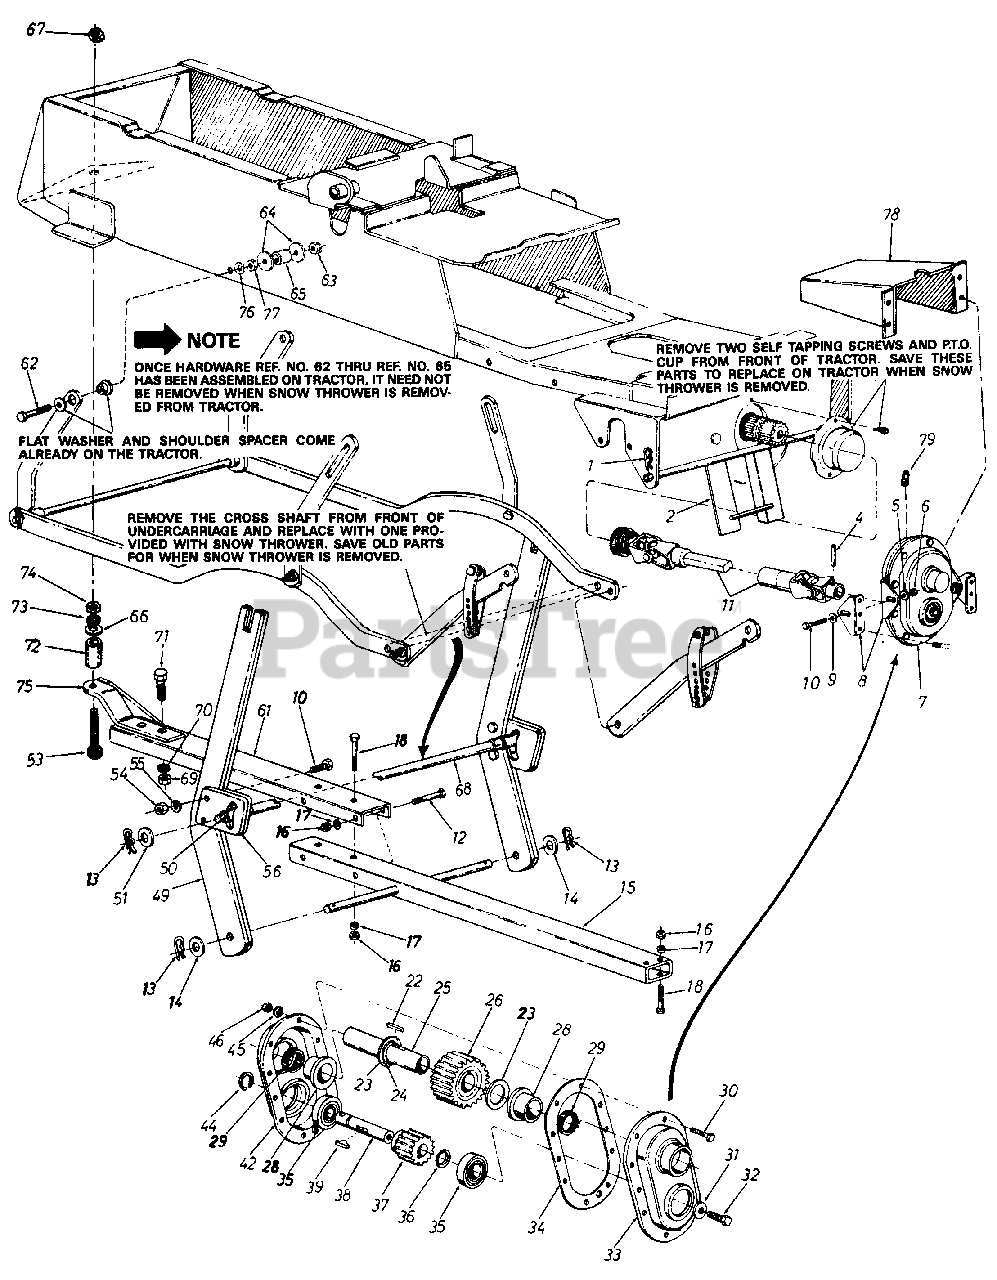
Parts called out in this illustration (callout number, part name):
1	Intern. Cotter Pin 3/4" Dia.
2	Guide Bracket Ass'y.
4	Roll Pin Spirol 5/16" Dia. x 2.5" Lg.
5	Belleville Wash. .341" I.D. x .88" O.D.
6	Hex Nut 5/16-18 Thd.*
7	Gear Box Ass'y. Comp.
8	Gear Box Support Brkt.
9	Belleville Wash. .341" I.D. x .88" O.D.
10	Hex Bolt 5/16-18 x 1.25" Lg. (Grade 5)
11	Universal Drive Shaft Ass'y.
12	Hex Bolt 3/8-24 x 4.50" Lg.*
13	Hair Pin Cotter
14	Fl.-Wash. .75" I.D. x 1.5" O.D.
15	Lift Shaft Ass'y.
16	Hex Ins. Jam L.-Nut 3/8-24 Thd.
17	L.-Wash. 3/8" I.D.*
18	Hex Bolt 3/8-24 x 2.75" Lg.
22	Hi-Pro Key 1/4" x 7/8" Dia.
23	Fl.-Wash. 1.31" I.D. x 2.00" O.D. x .060
24	Snap Ring for 1.25" Dia. Shaft
25	Gear Shaft 1.25" Dia. x 6.0" Lg.
26	28 Teeth Spur Gear
28	Flange Bearing 1.25" I.D. x 1.75" O.D.
29	Oil Seal 1.25" I.D. x 1.75" O.D. x.26
30	Hex Bolt 1/4-28 x .88" Lg.
31	Fl.-Wash. .40" I.D. x 1.25" O.D. x.160
32	Hex L.-Bolt 3/8-24 x 1.00" Lg.
33	Gear Housing Half-L.H.
35	Ball Bearing 1.00" I.D. x 2.00" O.D.
36	FL.-Wash. 1.03" I.D. x 1.63" x .090
37	15 Teeth Spur Gear
39	Woodrull Key 1/4" x 3/4" Dia.
42	Gear Housing Half-R.H.
44	Snap Ring for 1.00" Dia. Shaft
45	Spring Wash. 1/4" I.D.
46	Hex Nut 1/4-28 Thd.
51	Fl.-Wash. .62" I.D. x 1.12" O.D.
53	Hex Bolt 5/8-11 x 4.00" Lg.*
54	Hex Nut 5/16-18 Thd.*
55	L.-Wash. 5/16" I.D.*
62	Hex Bolt 3/8-24 x 2.50" Lg. (Grade 5)
63	Hex Jam L.-Nut 3/8-24 0 Thd.
64	Fl.-Wash. .375" I.D. x 1.00" O.D. x .135"
65	Spacer.375" I.D. x .625" O.D. x .445
66	Fl.-Wash. .62" I.D. x 1.12" O.D.
67	Hex Jam L.-Nut 5/8-11 0 Thd.
68	Cross Shaft Ass'y.
69	Hex Nut 1/2-13 Thd.*
70	L.-Wash. 1/2" I.D.*
71	Hex Bolt 1/2-13 x 1.25" Lg.
72	Spacer .65" I.D. x 2.12" Lg.
73	L.-Wash. 5/8" I.D.*
74	Hex Jam Nut 5/8-11 Thd.
77	Hex Nut 3/8-24 Thd.*
78	Drive Shaft Cover
79	Grease Fitting
